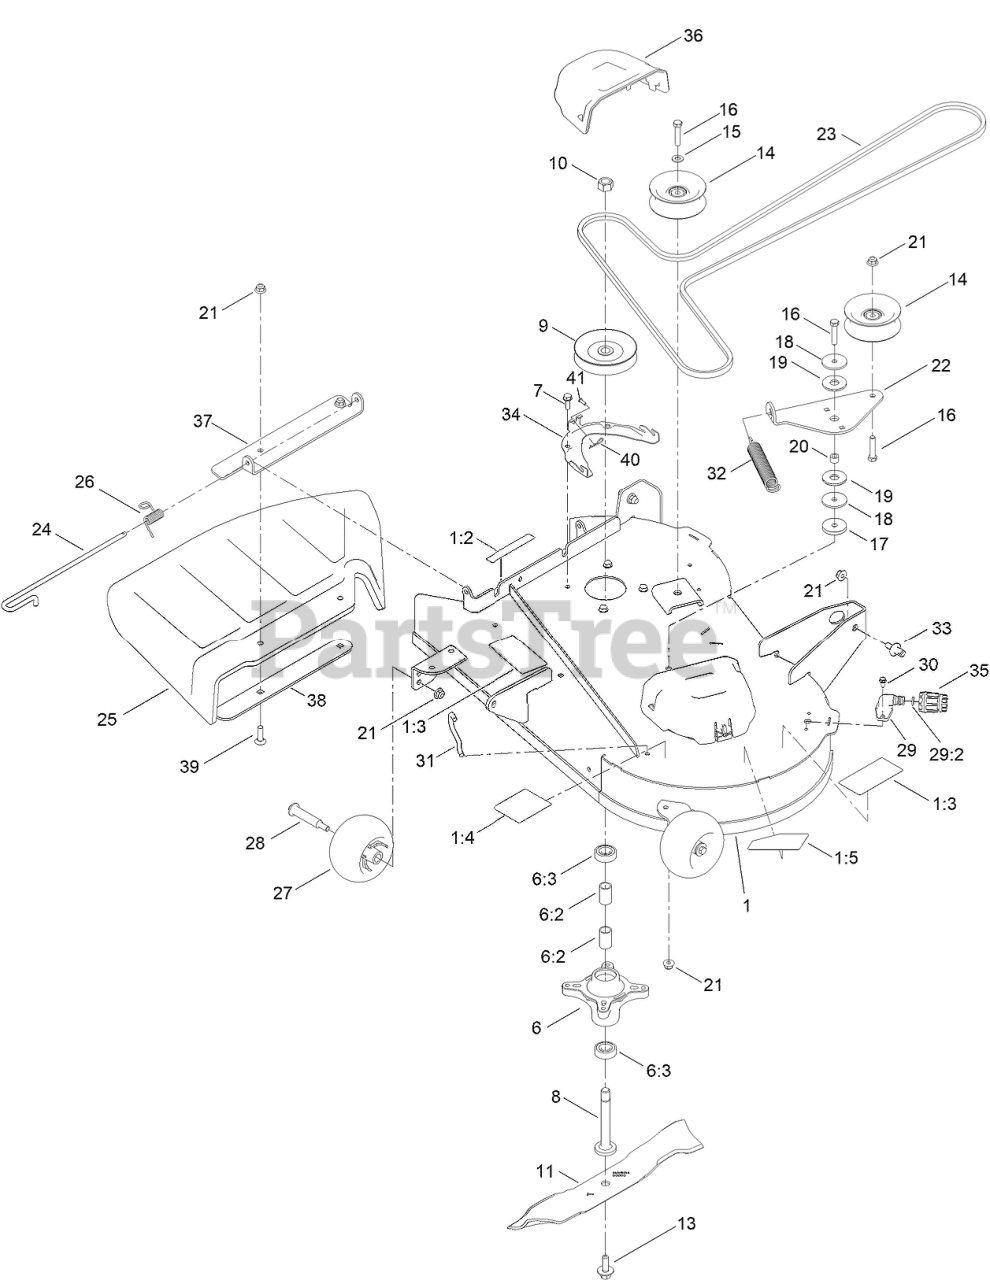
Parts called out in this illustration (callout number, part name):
1	34 INCH DECK AND DECAL ASM
1:2	DECAL-DANGER
1:3	DECAL-DANGER, DECK
1:4	DECAL-ROUTING, BELT
1:5	DECAL-DECK
6	SPINDLE ASM
6:2	SPACER
6:3	BEARING-BALL
7	SCREW-TAPTITE
8	SHAFT-SPINDLE
9	PULLEY ASM
10	NUT-HEX
11	BLADE 17.50 [BLACK]
13	BOLT-BLADE, SEMS
14	PULLEY-IDLER, FLAT
15	WASHER-FLAT
16	SCREW-HH
17	WASHER-PLAIN
18	WASHER-REBOUND
19	WASHER-FRICTION, COMPOSITE
20	SPACER
21	NUT-HF, NI
22	ARM-IDLER
23	BELT-V
24	PIN-CHUTE
25	DEFLECTOR-RUBBER
26	SPRING-TORSION
27	ROLLER-SCALP, ANTI
28	BOLT-SHOULDER
29	FITTING-WASHOUT
29:2	O-RING
30	SCREW-HWH
31	HOOK-RETURN SPRING
32	SPRING-EXTENSION
33	PIN-DECK
34	BRACKET-COVER, BELT
35	CONNECTOR-HOSE
36	COVER-BELT
37	BRACKET-DEFLECTOR, TOP
38	PLATE-DEFLECTOR, BOTTOM
39	SCREW-CARR
40	PIN-HAIR
41	SCREW
